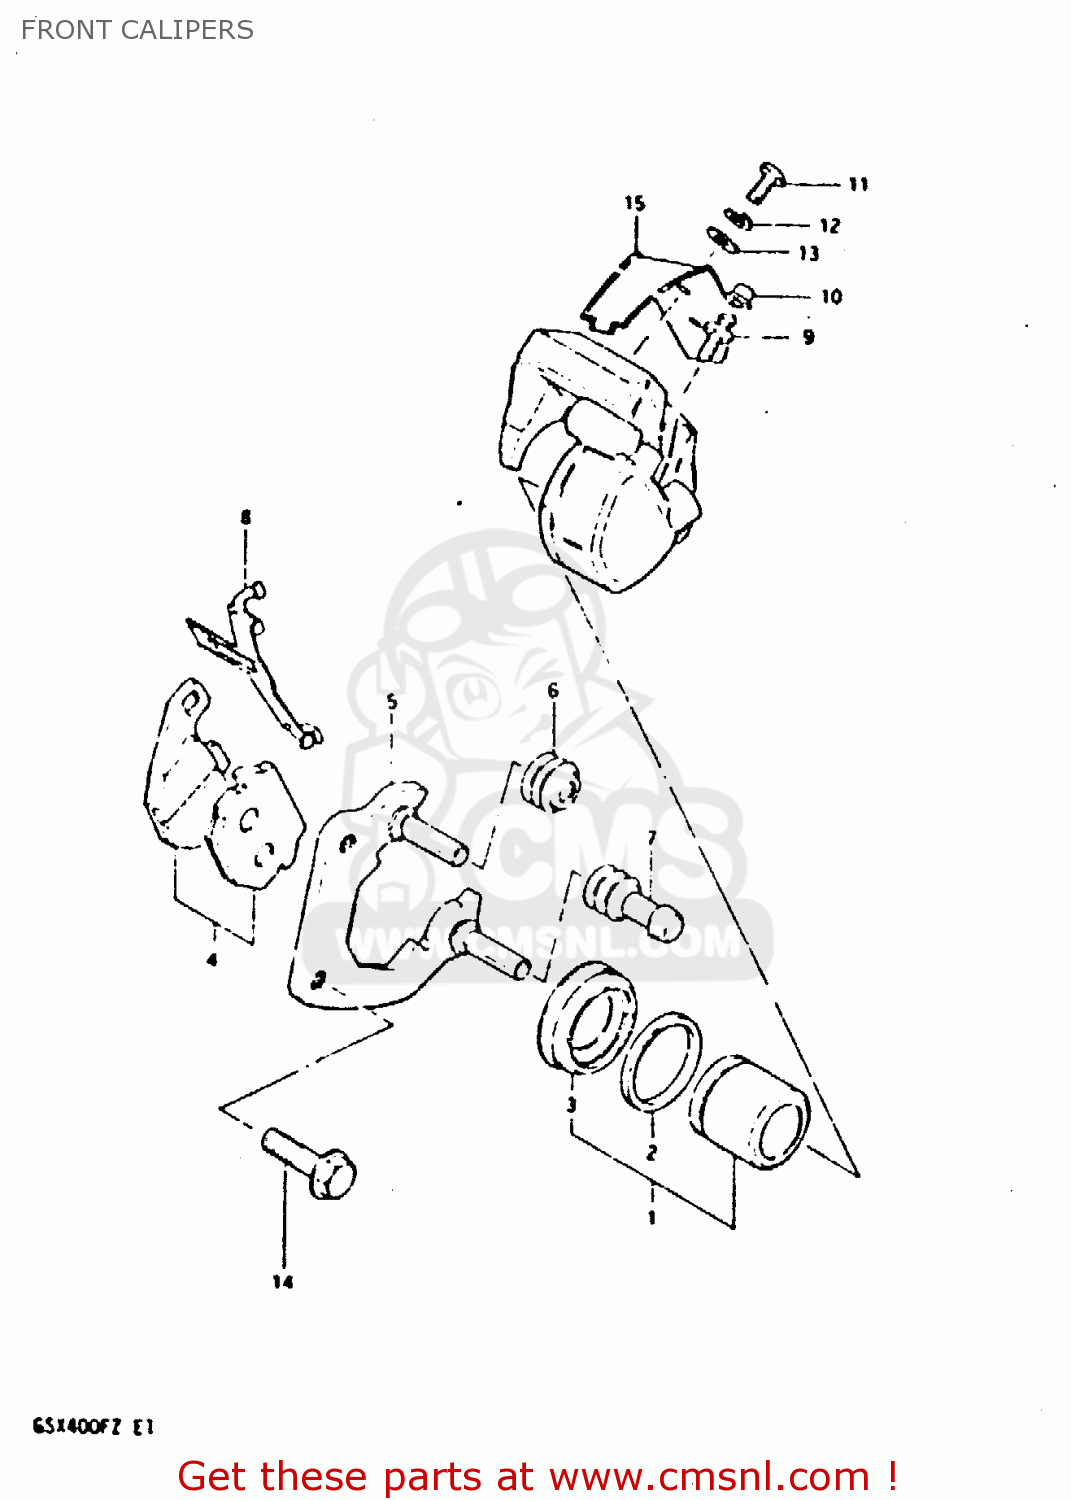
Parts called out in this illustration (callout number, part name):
1	PISTON SET
2	SEAL,PISTON
3	BOOT,PISTON
4	PAD SET
5	CARRIER,CALIPE
6	BOOT,AXLE
7	INSULATOR,AXLE
8	SPRING,PAD
9	BLEEDER
10	CAP,BREATHER
11	SCREW
12	LOCK WASHER
13	WASHER
14	BOLT
15	COVER
